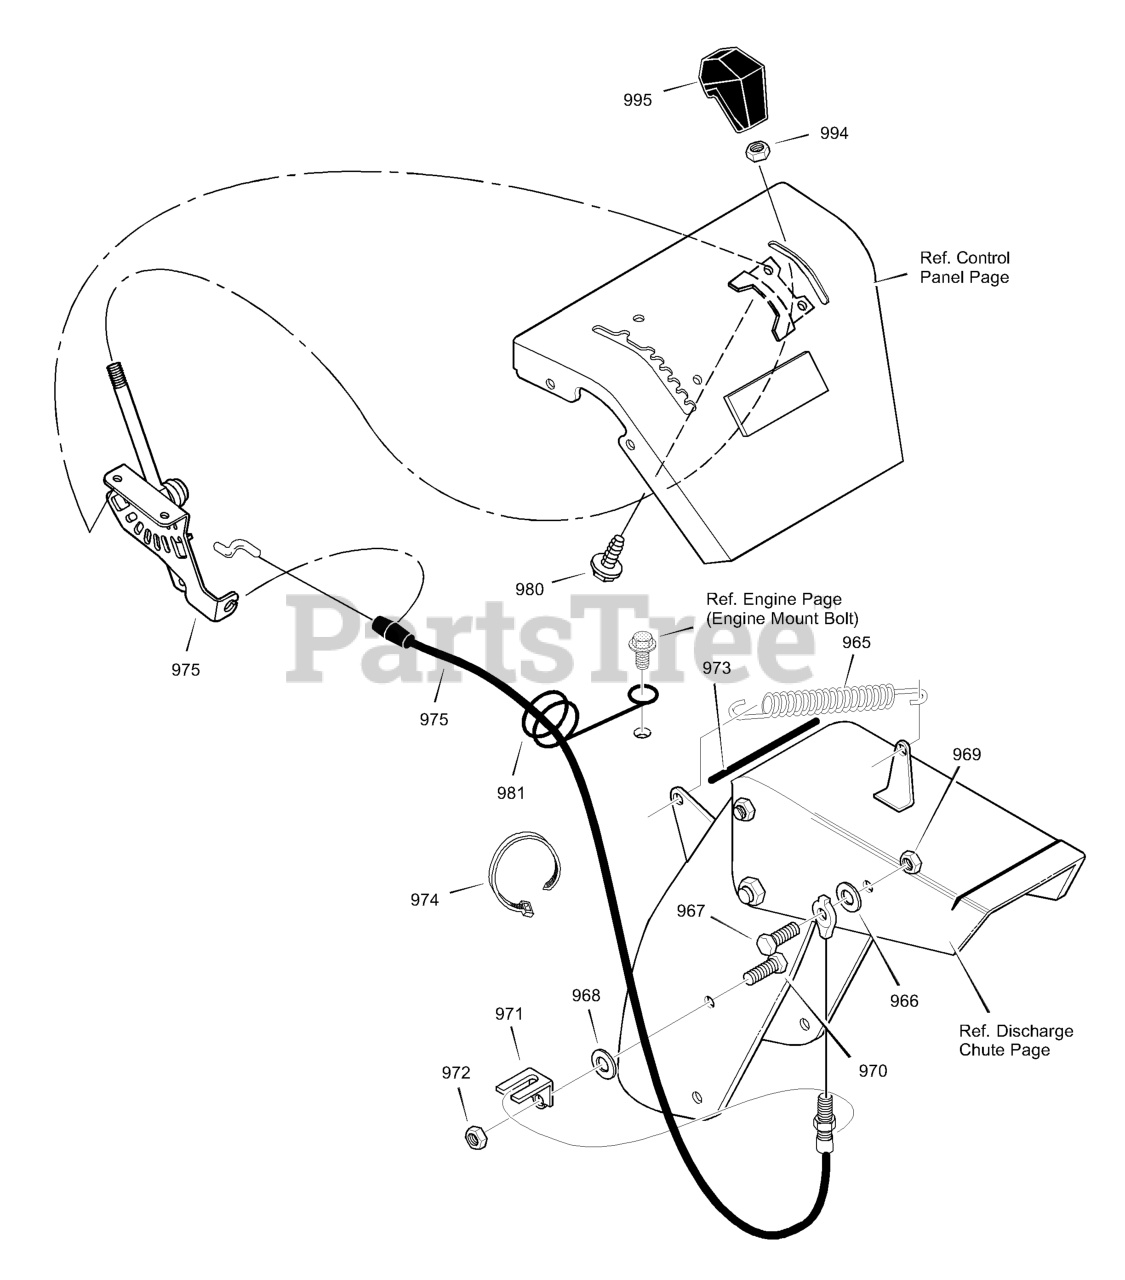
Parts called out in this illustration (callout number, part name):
965	TENSION SPRING
966	FLATWASHER
968	FLATWASHER
970	SCREW
971	BRACKET, CABLE CHUTE
972	NUT
973	TRIM STRIP, BLACK
974	TIE, CABLE
975	ASSY, CHUTE DEF. CONTROL
980	SCREW
981	WIRE FORM, REMOTE CHUTE CABLE
995	KNOB, SHIFT (BLACK)
